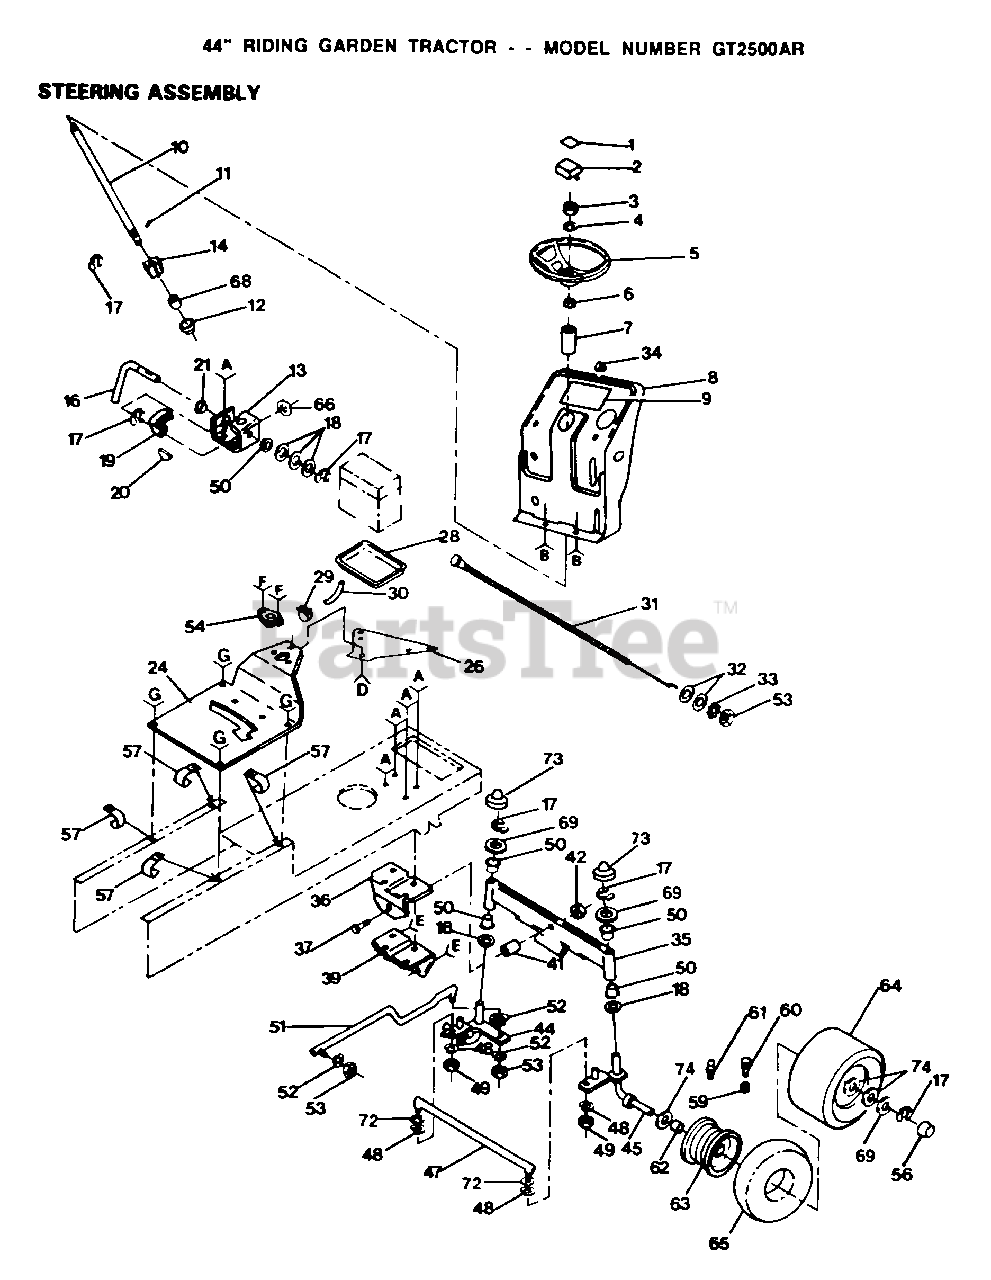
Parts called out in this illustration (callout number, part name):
2	INSERT-WHEEL LT
4	WASHER
6	ADAPTER LT
7	SLEEVE LTV
10	SHAFT STR HYT
12	BUSHING
14	GEAR PINION T
16	ROD STEERING T
17	RING
18	WASHER .T
19	GEAR.SECTOR.HYT
20	KEY-WOODRUFF LT
21	NYLINER T
28	"TRAY T, BATTERY"
29	HOSE CLAMP T
32	WASHER
33	LOCKWASHER
34	PLUG-DASH T
35	FRONT AXLE
36	SUPPORT-SADDL T
37	BOLT LT
39	SUPPORT.SADDLE.FT
41	BEARING
42	"NUT-LOC,FLANGE LT"
44	SPINDLE-LH LT
48	LOCKWASHER
49	NUT
50	COL. SRTG. BEAR.
51	LINK-DRAG LT
52	LOCKWASHER
56	HUB CAP
57	CLIP T
59	VALVE CAP
60	VALVE STEM LT
61	FITTING LT
62	"FLANGE, BEARING"
65	TUBE.5.3/4.5/6
68	SHAFT SPACER LT
69	WASHER
72	WASHER M
73	CAP
74	WASHER
